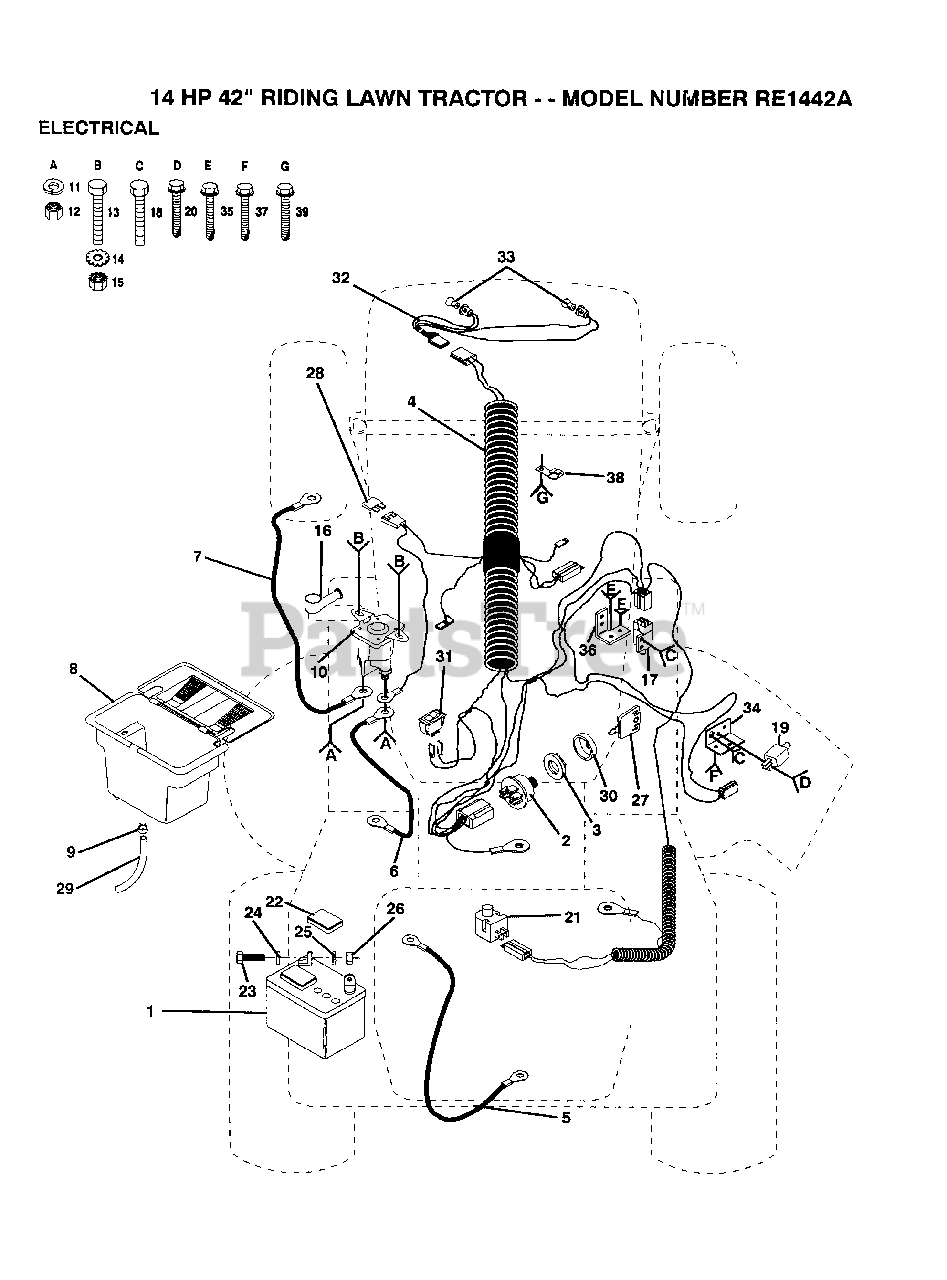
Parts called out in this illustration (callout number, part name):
3	NUT IGNITION
4	IGN HARNESS
5	CABLE T
7	"CABLE T, BATTERY"
9	HOSE CLAMP T
12	NUT
13	BOLT
15	NUT
17	SWITCH INTERLOCKT
18	SCREW
19	SWITCH-INTER. GT
20	SCREW
21	SWITCH SEAT
22	"CAP,BATTERY "
23	BOLT LT
24	WASHER
25	LOCKWASHER
27	KEY
28	FUSE HYT
31	SWITCH LT
34	BRACKET LT
35	SCREW
36	SWITCH BRACKET
37	SCREW
38	INSUL CLIP T
39	FUSE 30 AMP AUTO GREEN
